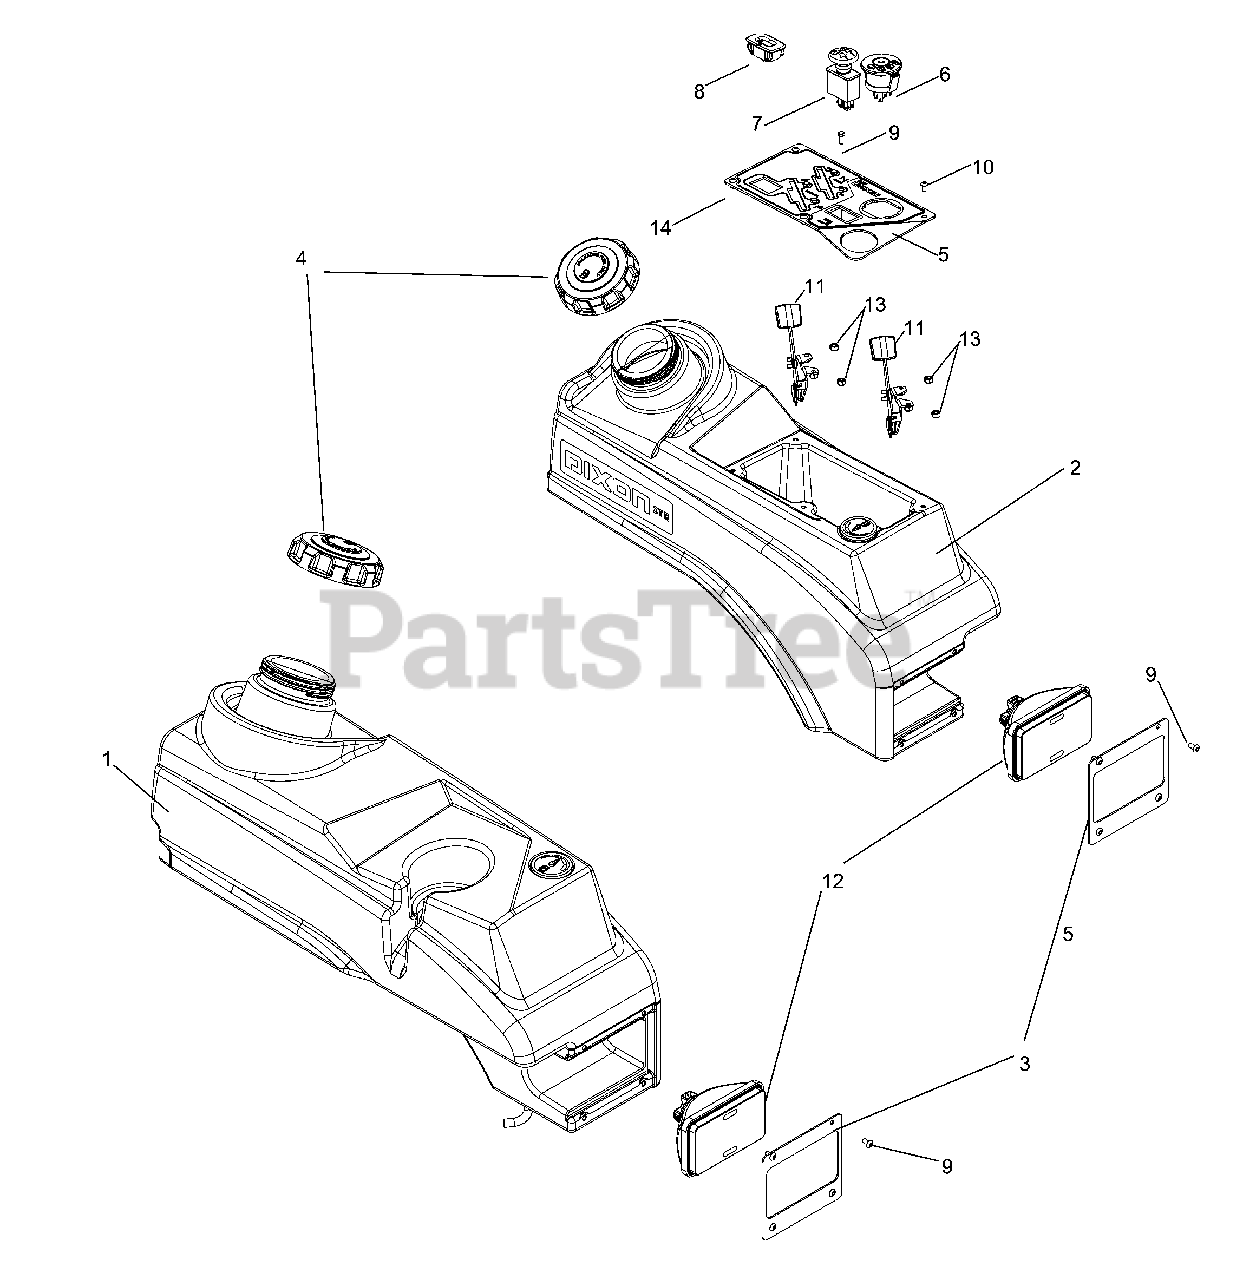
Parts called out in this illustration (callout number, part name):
1	TANK, FUEL, LT
2	TANK, FUEL, RT
3	PLATE LIGHT
4	FUEL CAP ANTI-SPLASH
5	CONTROL PANEL
6	IGNITION SWITCH
7	SWITCH, BLADE
8	HOUR METER
9	HCS #10-24 X 1/2
10	SCR #10-24 X 3/8 SKT HD BLK OX
11	CHOKE CABLE
13	NUT 10-24 NYLOC
14	DECAL, CONTROL
